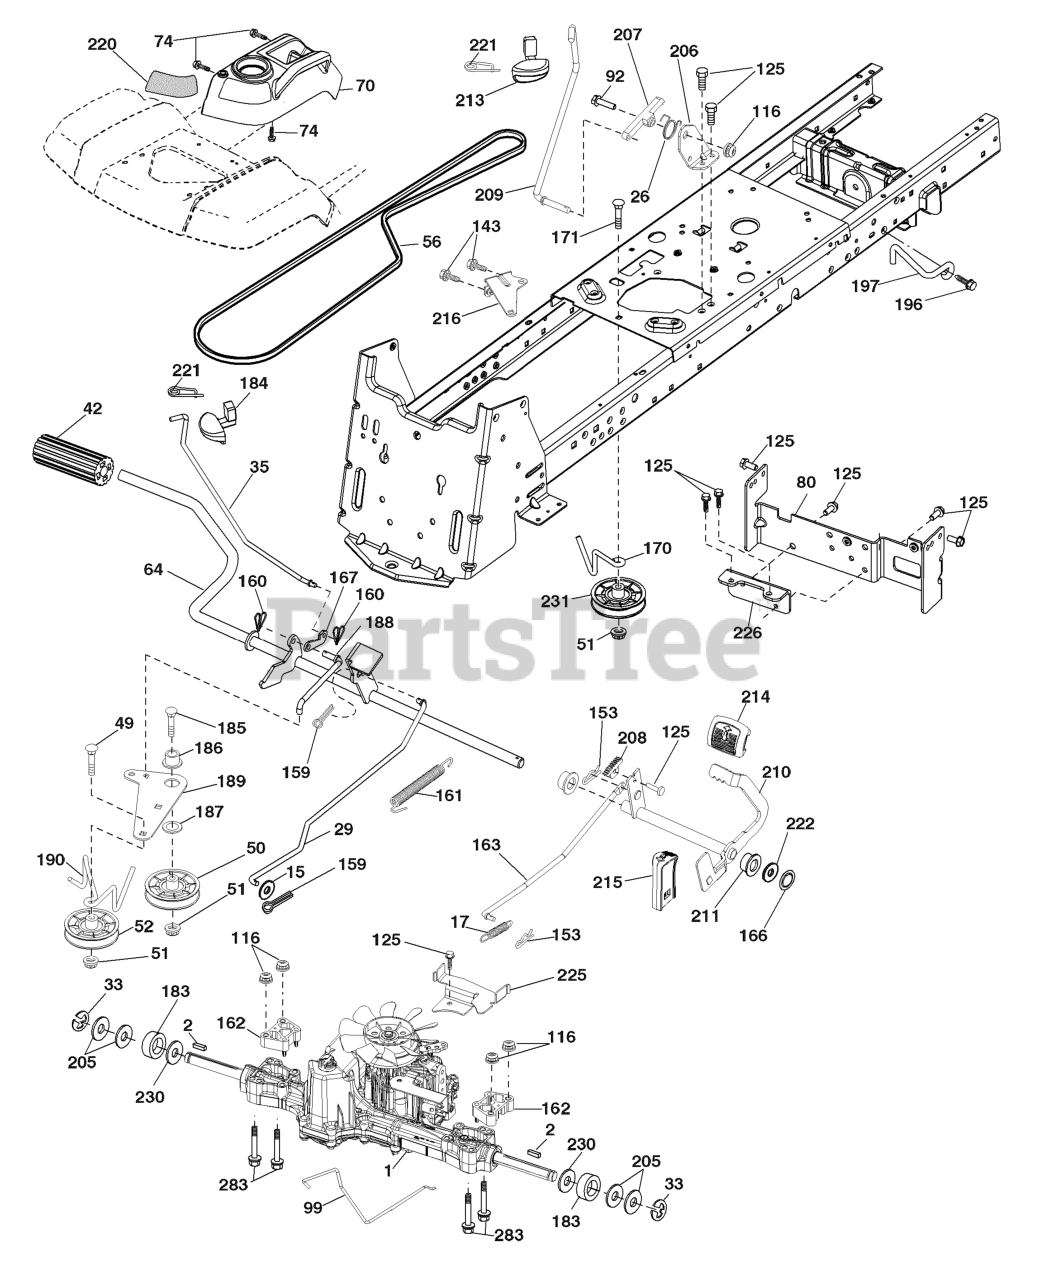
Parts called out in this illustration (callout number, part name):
1	TRANSAXLE, TUFFTORQ K46
2	SQUARE KEY
15	WASHER
17	SPRING.BRAKE.K46.GREEN
26	SPRING.RETURN.CRUISE
29	ROD.BRAKE.K46
35	ROD.BRAKE.PARKING.GT.H
42	PEDAL COVER T
50	IDLER.FLAT.910.OFFSET
51	NUT LOCK FLG 3/8-16 UNC
52	IDLER.V-GROOVE.910.OFFSET
56	V-BELT.MOWER.92.40.42/K46
64	SHAFT.ASM.PEDAL.BRK.CNTR
70	RP CONSOLE.ASM.PCH.W/TB
74	SCREW.HI-LO.CONSOLE
80	STRAP TORQUE
92	BOLT
99	ROD.SPRING.BYPASS.K46.TEX.GT
116	NUT LOCK HEX FLANGE 5/16-18
125	SCREW
143	Screw Thdrol 5/16-18 x 1/2
153	RETAINER M
159	COTTER PIN
160	RETAINER CLIP
161	SPRING, RETURN LT
162	SPACER TRANS
163	ROD.CONTROL.PEDAL.K46
166	NUT.PUSH.625.2006
167	LATCH.BRAKE.SPRING
170	KEEPER.CENTER SPAN.1.688
183	SPACER AXLE
184	HANDLE.PARKG.BRK.HUSQ X667
185	BOLT
186	SPACER.RETAINER
187	WASHER 12/32X2X10GA
188	RP.LINK.CLUTCH.GROUND.DRIVE
189	BELLCRANK.GROUND.DRIVE.TEX.
190	KEEPER.BELLCRANK.DRIVE
196	SCREW 3/8-16X1
197	BRKT.ANIT-ROTATION.CLUTCH
206	BRKT.MOUNT.LATCH.CRUIS
207	LATCH.CONTROL.CRUISE
208	GEAR.SECTOR.CONTROL.CR
209	ROD.CONTROL.CRUISE.GT.
210	ROCKER.ASM.PEDAL.CONTR
211	BEARING.NYLON
213	KNOB.CONTROL.CRUSIE.HU
214	PEDAL.FORWARD.TEX.GT.4
215	PEDAL.REVERSE.TEX.GT.4
216	BRACKET.PULLEY.IDLER.W/TEX
220	REFLECTOR.RH.TEX GT
221	RETAINER.SPRING.CLIP.H
222	WASHER
225	KEEPER.BELT.TRANSAXLE.K46
226	BRACKET.MOUNT.TORQUE.K46.TLT
230	WASHER.HARDENED
231	IDLER.V-GROOVE.1.688.OFFSET
283	HEX BOLT, 5/16-18 X 4.25 GR. 5
